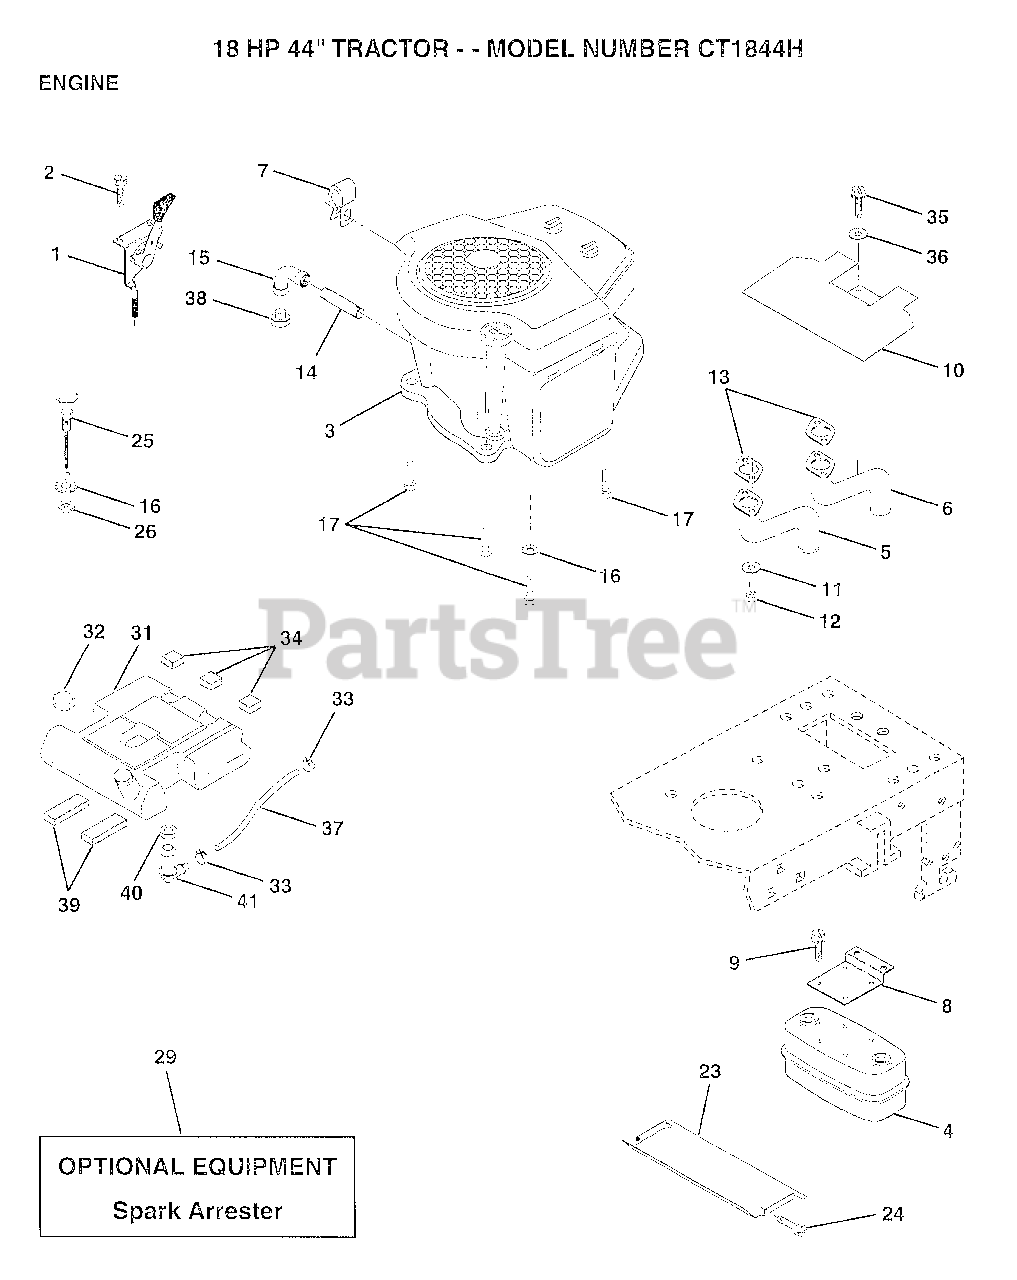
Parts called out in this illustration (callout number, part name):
2	SCREW LT
5	EXHAUST.B&S.18.LH
6	EXHAUST.B&S.18.RH
7	CLIP T
8	BRACKET MUFFLER
9	SCREW ST
10	SHIELD HEAT LT
11	LOCKWASHER
14	PIPE NIPPLE LT
15	ELBOW
16	LOCKWASHER
17	SCREW LT
23	HEAT SHIELD
24	SCREW
25	CHOKE CONTROL
32	CAP ASM FUEL
33	HOSE CLAMP
34	PAD-SPACER LT
35	SCREW
36	WASHER
37	FUEL LINE T
39	PAD IDLER TI
40	BUSHING OUTLET T
41	STEM.TANK.FUEL
